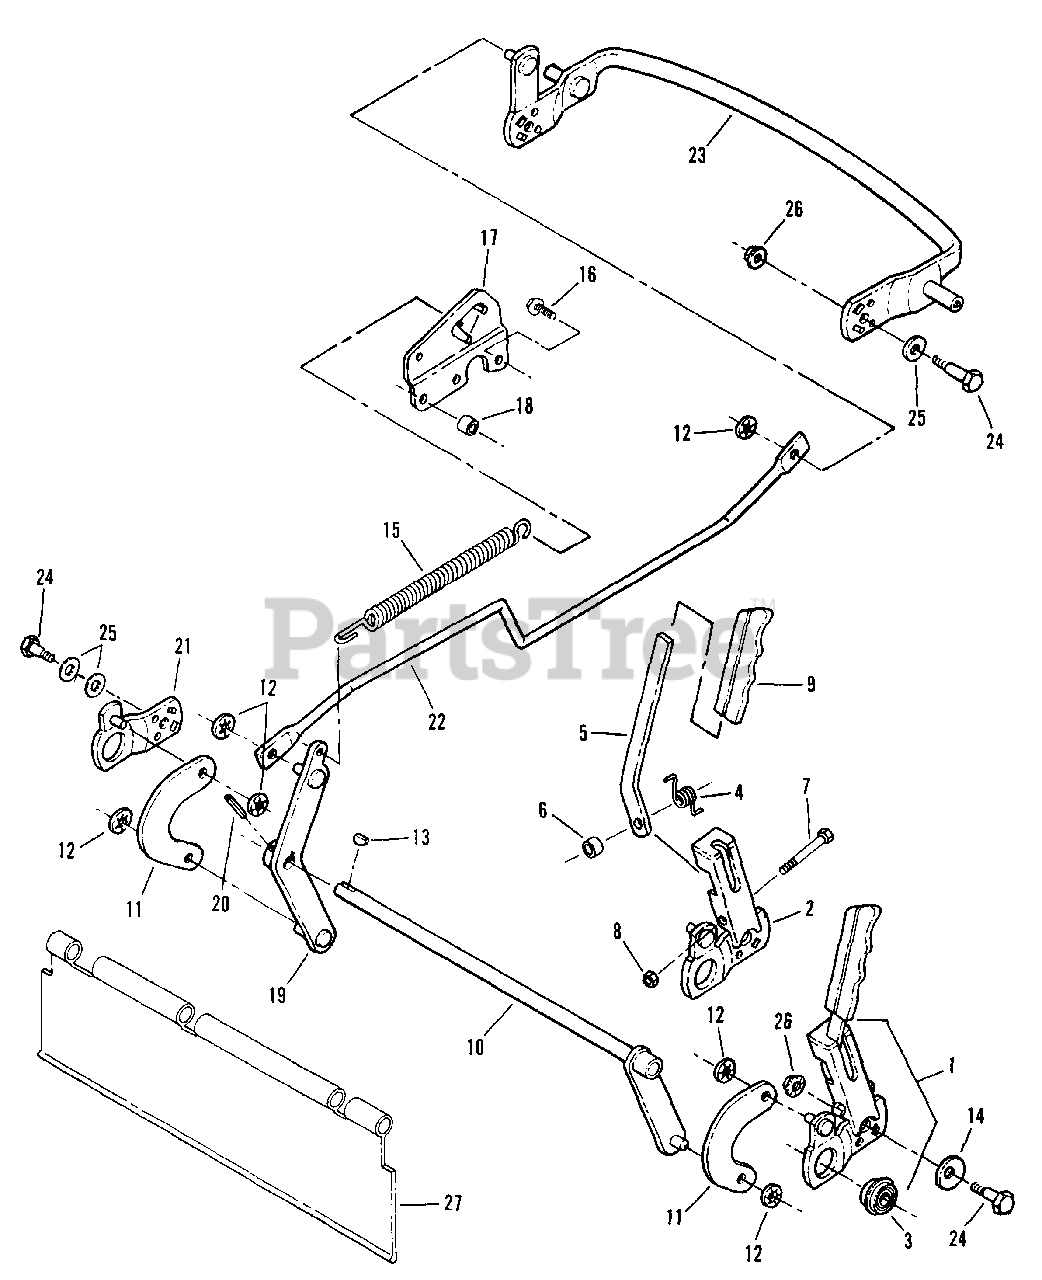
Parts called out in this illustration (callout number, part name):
1	ASSEMBLY, Wheel Arm Height Lever
2	WELDMENT, Wheel/Arm
3	BEARING
4	SPRING, Torsion Return
5	HANDLE, Lift
7	SCREW, 5/16-18 x 2" Hex Head Cap
8	NUT, 5/16-18 Hex Center Lock
9	GRIP, Handle
10	WELDMENT, Rear Link (Right Hand)
11	LINK, Intermediate Rear
12	RETAINER, 3/8 Wheel
13	KEY, 5/32 x 5/8" #505 Woodruff
14	WASHER, 1/2 Belleville
15	SPRING, Extension
16	SCREW, 1/4-20 x 7/8" Self-Tapping (Torx)
17	BRACKET, Spring
19	WELDMENT, Rear Link (Left Hand)
20	PIN, 3/16 x 1" Roll
21	ASSEMBLY, Wheel Arm/Bearing (Left Hand)
23	WELDMENT, Front Wheel Arm
24	SCREW, 5/16-18 x 29/32 Shoulder
25	WASHER, 17/32 Wave
26	NUT, 5/16-18 Hex Flange Center Lock
27	SHIELD, Trail
